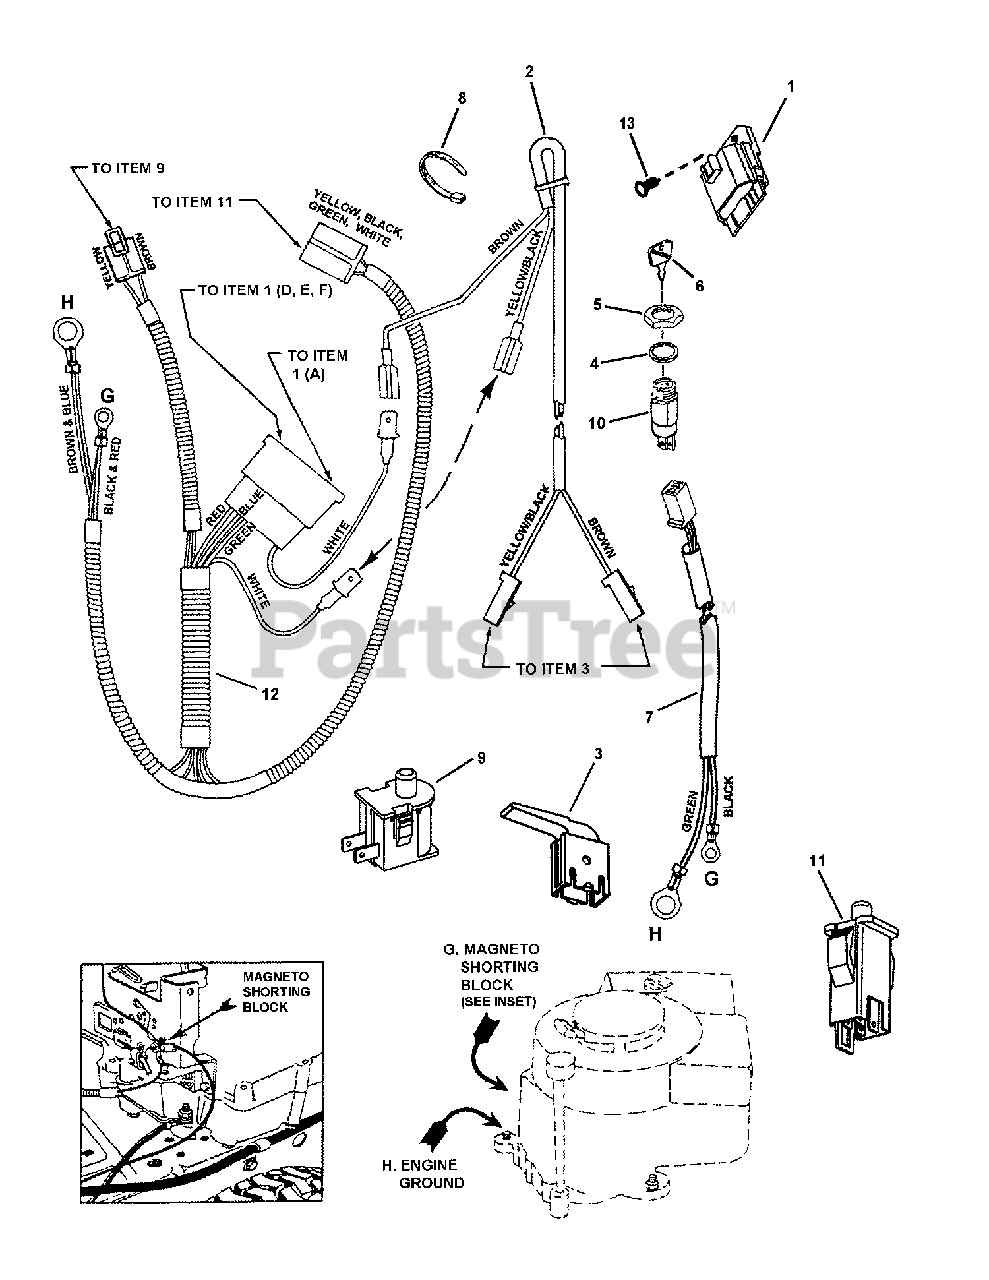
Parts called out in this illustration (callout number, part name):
1	INTERLOCK MODULE, Briggs
2	HARNESS, (Deck Interlock Wiring)
3	SWITCH, Deck Interlock (NO)
4	WASHER, 5/8" Internal Tooth Lock
5	NUT, 5/8-32 Hex
6	KEYS, BLISTER PK KIDS+MWRS DON'T MIX,DOM
7	HARNESS, Ground (Recoil Start)
8	CABLE TIE, 7"
9	SWITCH, Seat (NC)
10	SWITCH, Ignition, (2-Pole) (Recoil Start)
11	SWITCH, Operator Presence Control (OPC) Traction (NC/NO)
12	HARNESS, Operator Presence Control (OPC) Wire
13	FASTENER, 1/4" Ratchet
